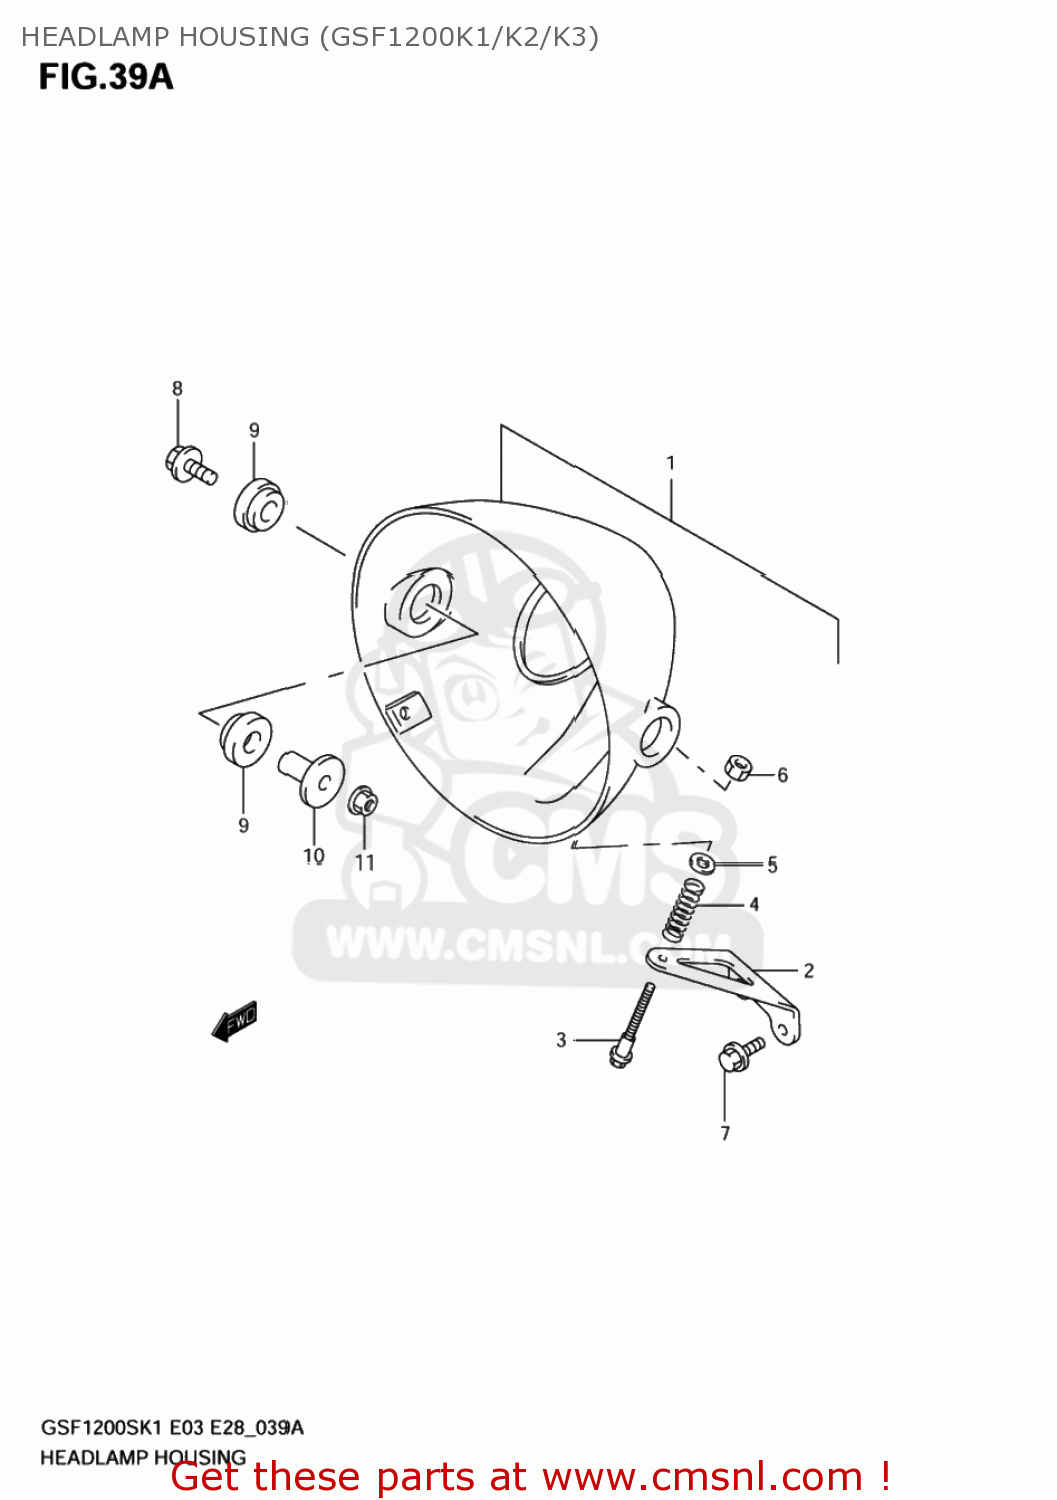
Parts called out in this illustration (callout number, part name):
1	HOUSING ASSY,HEADLAMP
2	PLATE,HEADLAMP HOUSING
3	BOLT,HEADLAMP ADJUSTER
4	SPRING,HEADLAMP ADJUSTER
5	WASHER
6	NUT,HEADLAMP ADJUSTER
7	BOLT
8	BOLT
9	CUSHION
10	SPACER(8.6X12X20)
11	NUT
